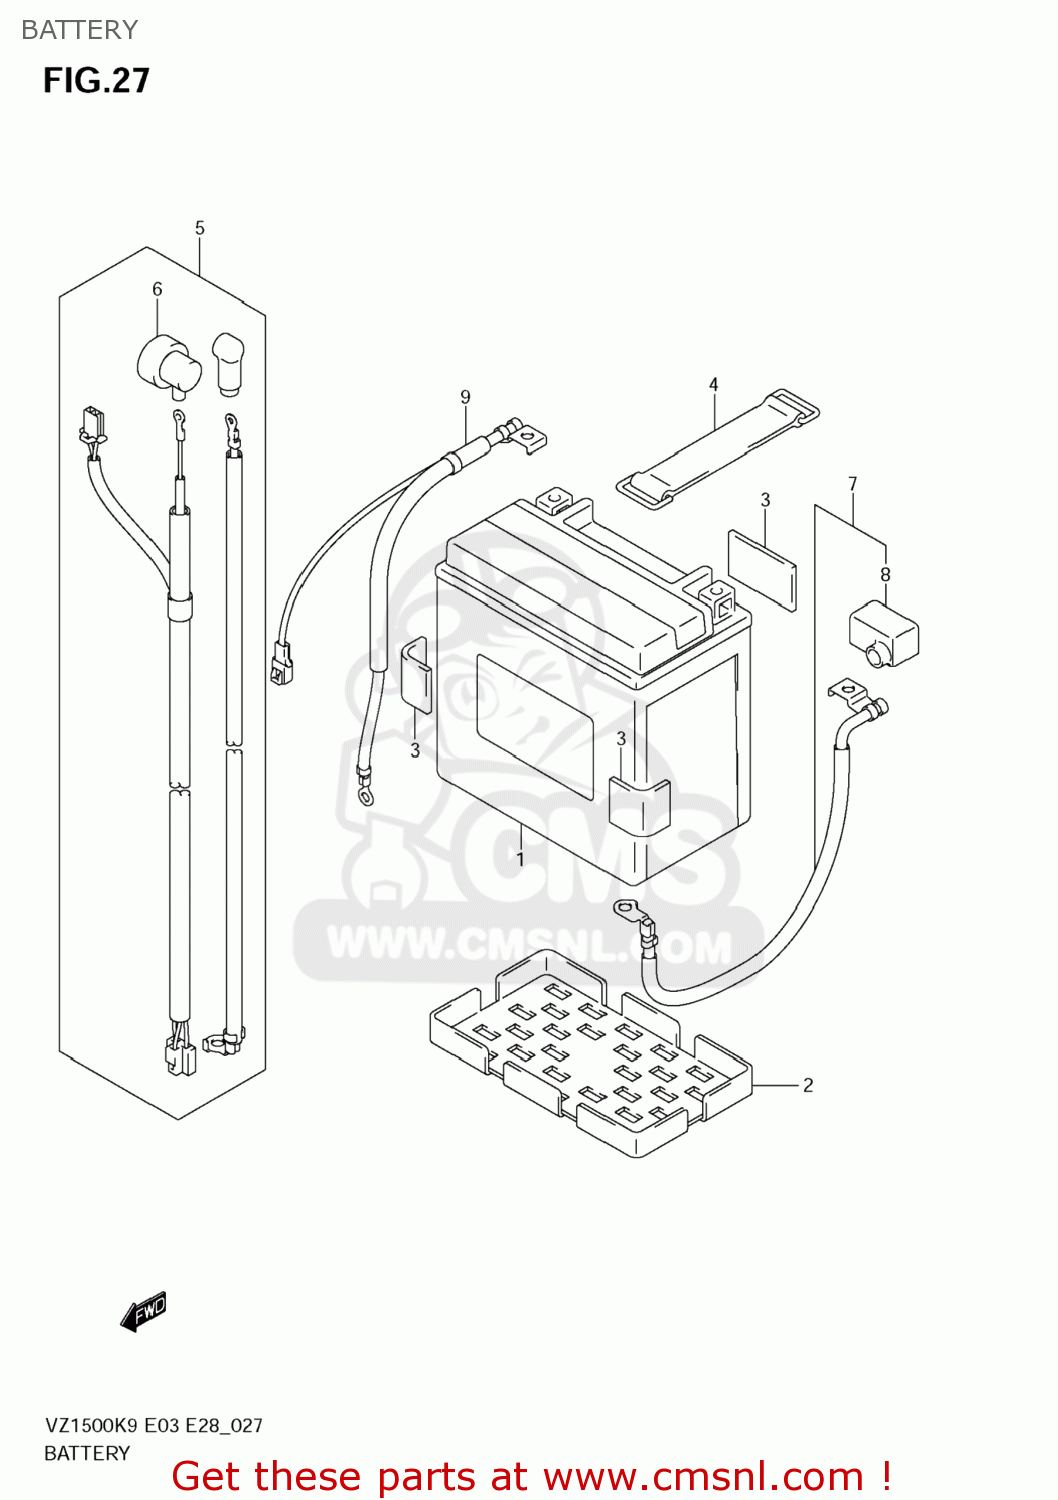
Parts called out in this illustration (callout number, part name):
1	BATTERY ASSY,F
2	PROTECTOR,BATTERY
3	CUSHION(30X50X3)
4	BAND
5	WIRE,STARTER MOTOR LEAD
6	CAP,OIL PRESSURE SWITCH
7	WIRE,BATTERY PLUS LEAD
8	CAP,BATTERY PLUS
9	WIRE,BATTERY MINUS LEAD
